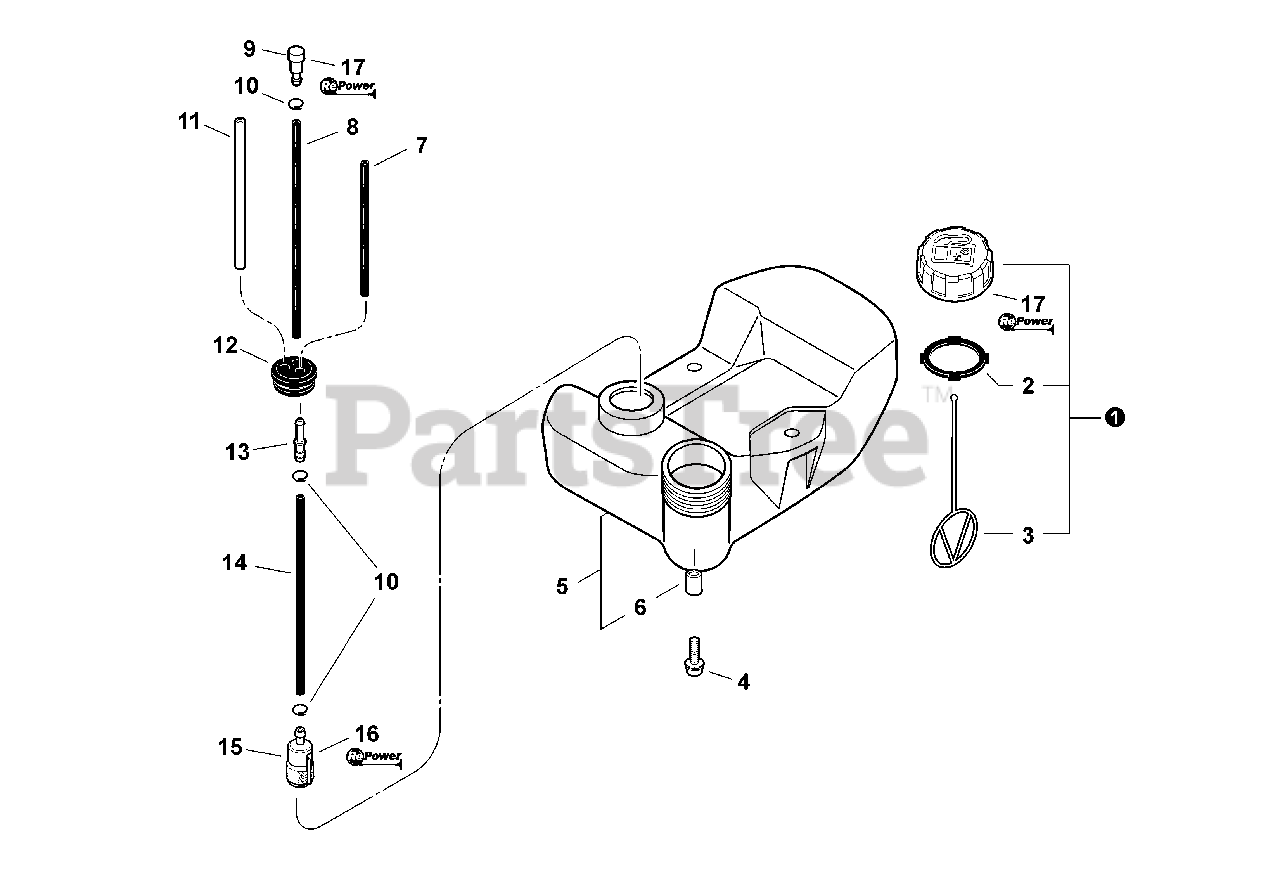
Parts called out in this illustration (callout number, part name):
1	CAP ASY - ORANGE
3	CONNECTOR, CAP
4	SCREW - 5×16
5	FUEL TANK ASY
7	PIPE - 3×5×67 -- BLACK
8	PIPE - 3×6×115 -- BLACK
9	VENT, FUEL TANK
10	CLIP - 6.5
11	PIPE - 3×6×80 -- CLEAR
12	GROMMET
13	CONNECTOR, FUEL PIPE
14	PIPE - 3×6×110 -- BLACK
15	FILTER, FUEL
16	RePower TUNE-UP KIT
16	RePower FILTER KIT
17	RePower CAP AND VENT KIT
